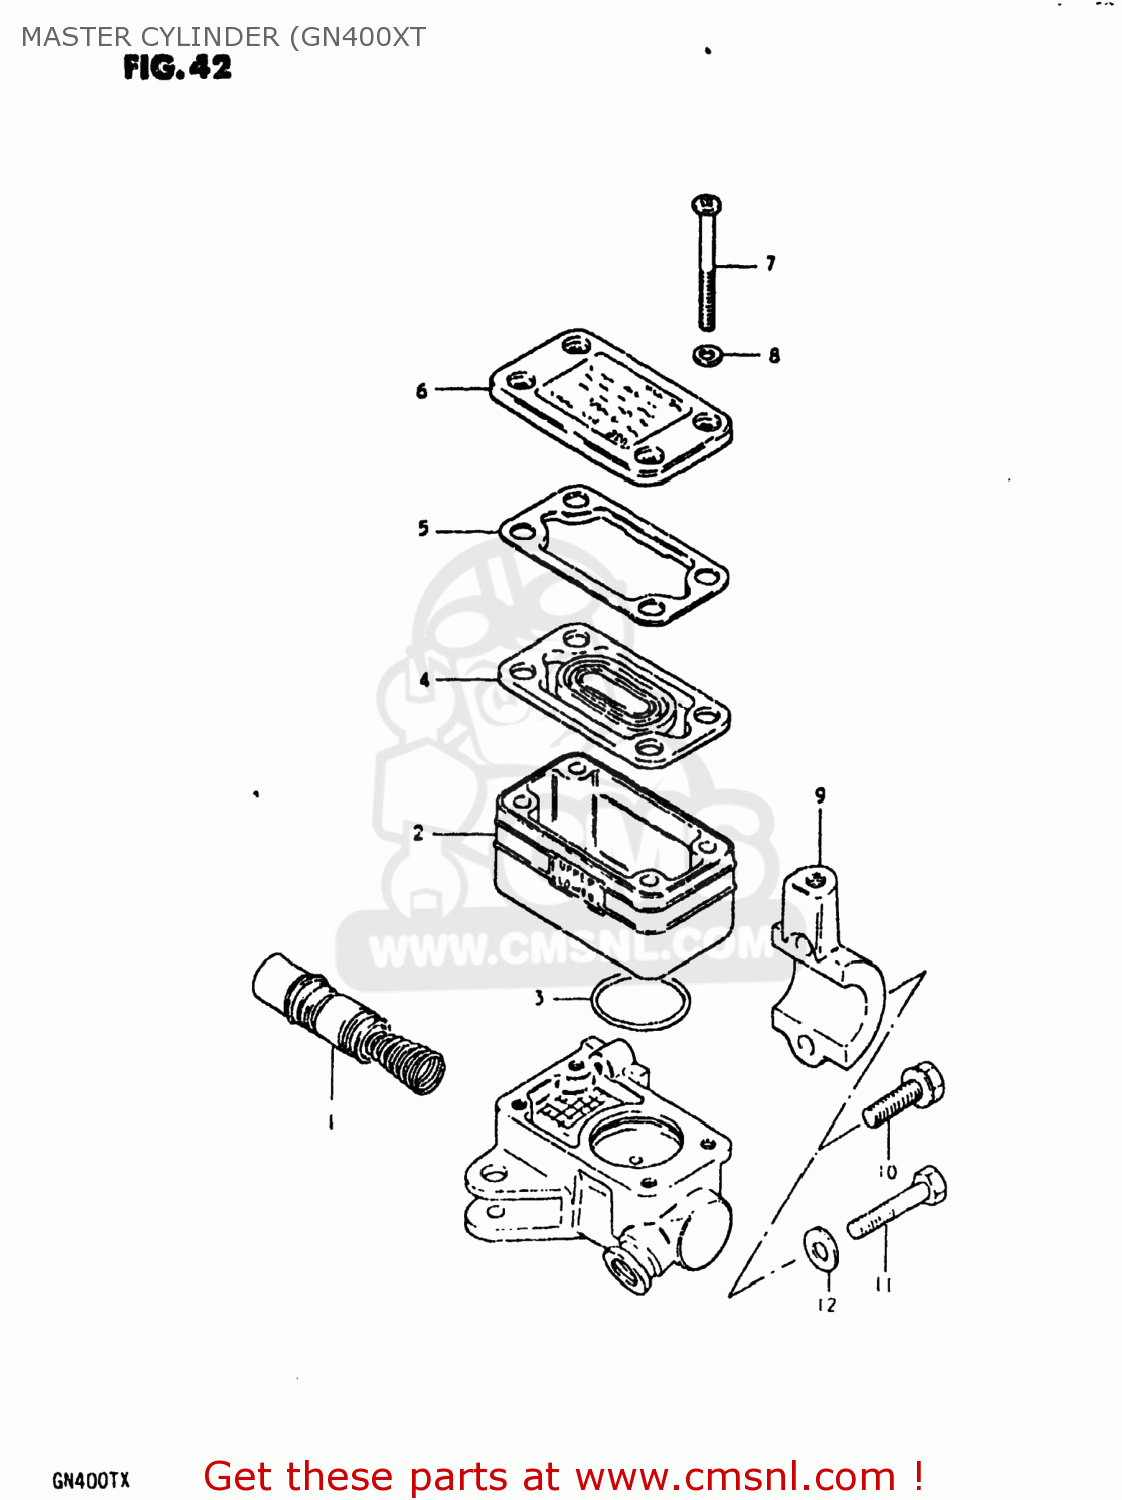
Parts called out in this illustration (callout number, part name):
0	CYLINDER ASSEMBLY,MASTER
1	PISTON & CUP SET
2	RESERVOIR
3	O RING
4	DIAPHRAGM
5	PLATE,DIAPHRAGM
6	CAP
7	SCREW
8	WASHER
9	HOLDER
10	BOLT,MASTER CYLINDER H
11	BOLT
12	WASHER
